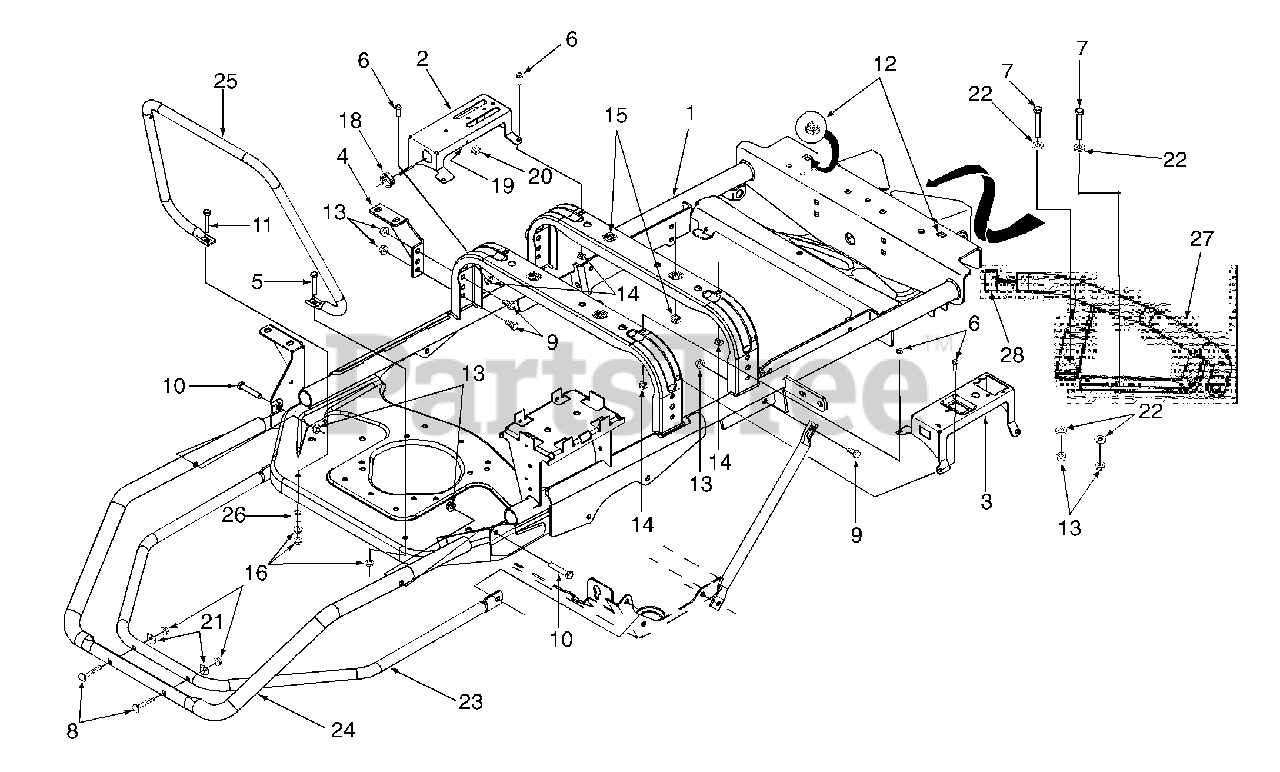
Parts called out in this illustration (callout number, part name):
6	Screw, Hex Wash. Hd. Tapp 1/4-20 x .625
7	Screw, Hex Cap 3/8-16 x 1.50 GR5
8	Screw, Curved Hd. Carriage 5/16-18 x 2.02
9	Screw, Hex Cap 3/8-16 x 3/4 GR5
10	Screw, Hex Cap 3/8-16 x 2 GR5
11	Screw, Hex Cap 5/16-18 x 1.75 GR5
12	Nut, Retainer, 3/8-16
13	Nut, Hex Flange Lock, 3/8-16
14	Nut, Retainer, 1/4-20
15	Nut, Retainer, 3/8-16
16	Nut, Hex Flange Lock, 5/16-18 GR5
19	Rivet, Pop, .125
20	Clip, Spring
21	Washer, Saddle
22	Washer, Flat, .406 x .875 x .105
